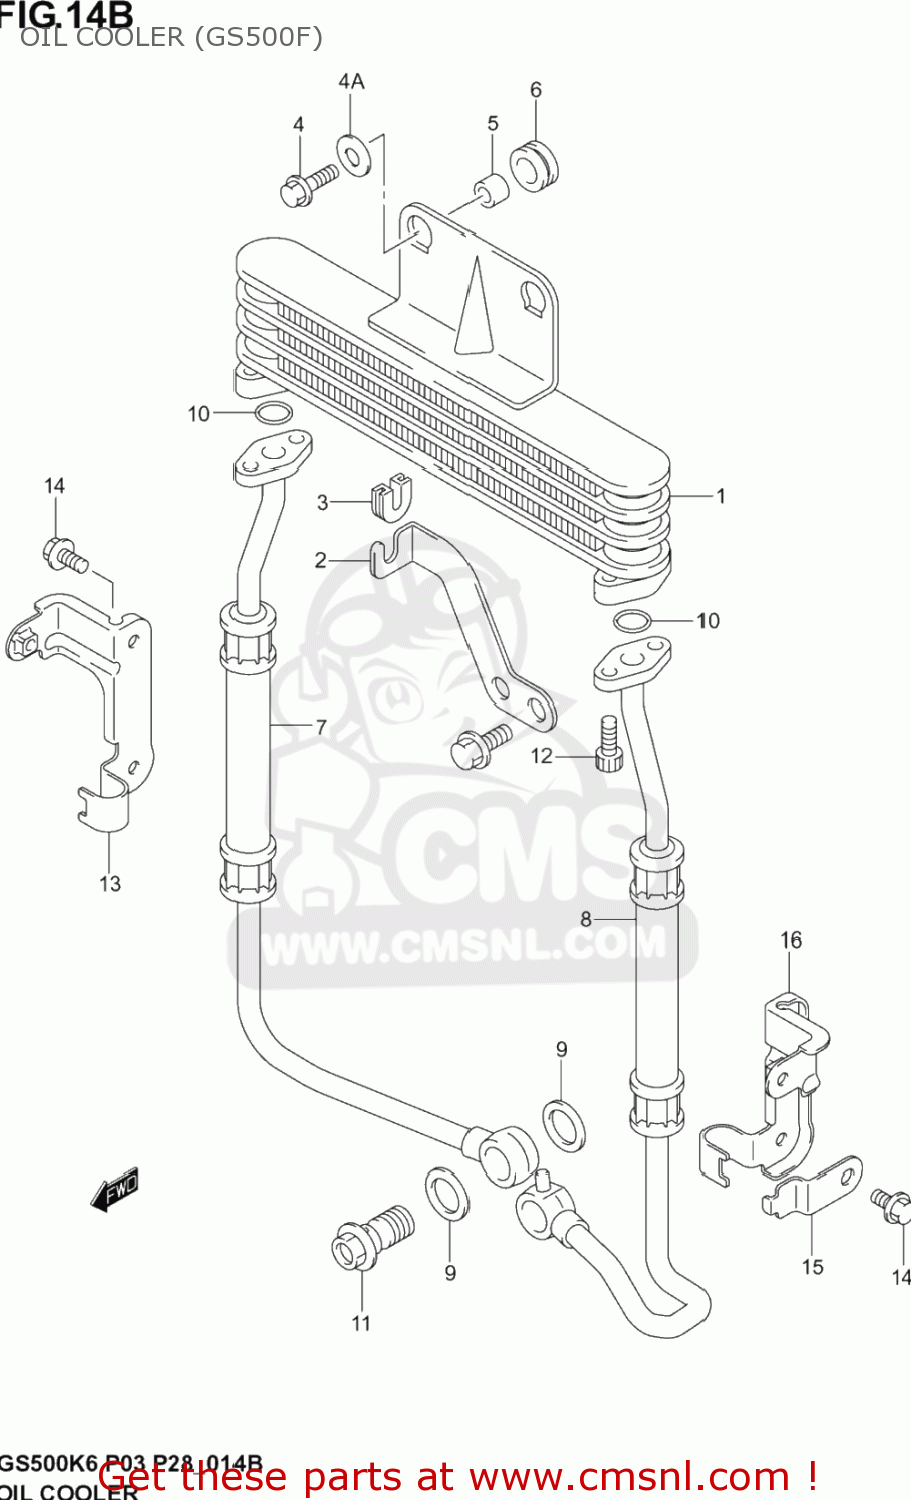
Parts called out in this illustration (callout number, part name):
1	COOLER ASSY,OIL
2	BRACKET,OILCOO
3	CUSHION
4	BOLT
4A	WASHER
5	SPACER (6.5X10X10)
6	CUSHION
7	HOSE,OIL COOLER,R
8	HOSE,OIL COOLER,L
9	GASKET(14X20X1.5) (NAS)
10	O-RING
11	BOLT UNION
12	BOLT
13	CLAMP, OIL HOS
14	BOLT OIL LEVEL
15	GUIDE, OIL HOS
16	CLAMP, OIL HOS
